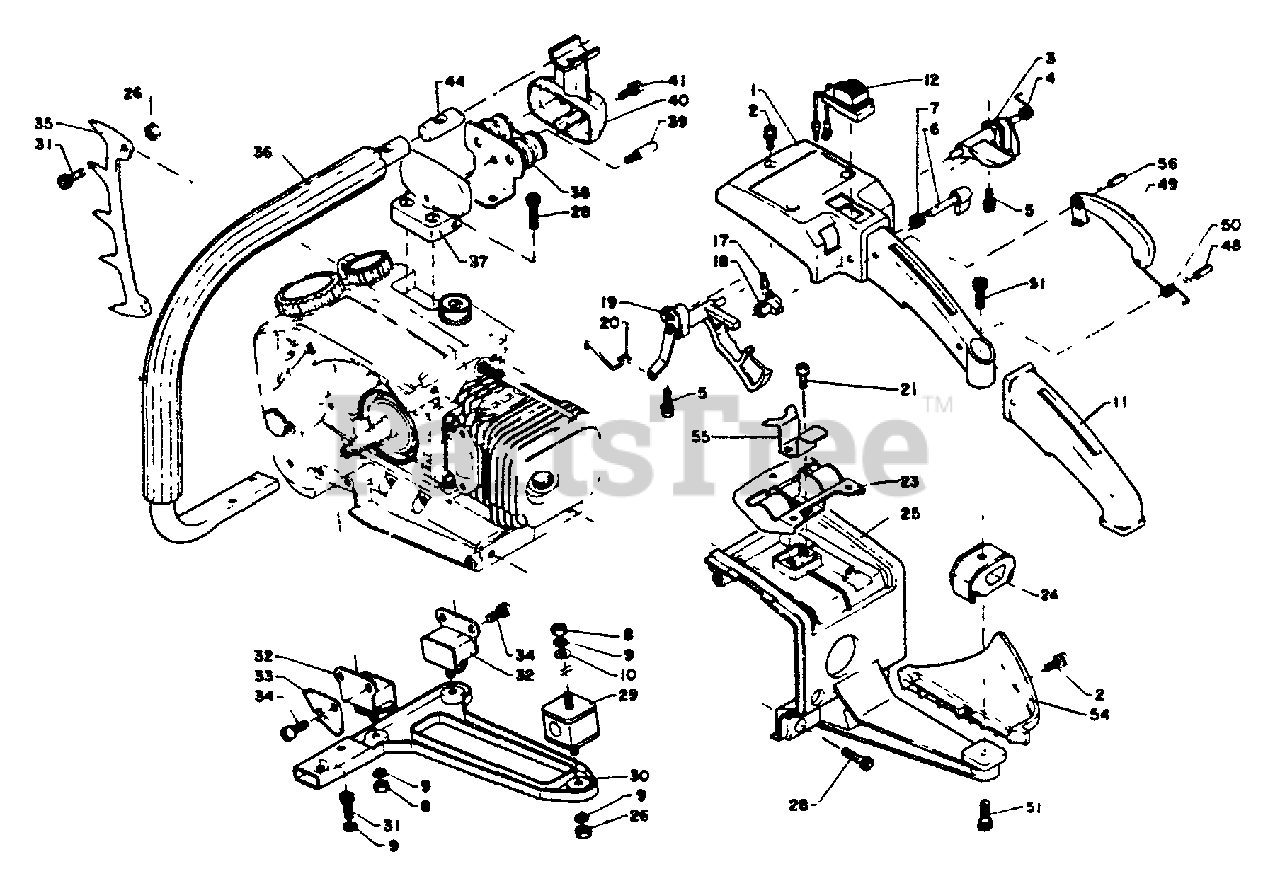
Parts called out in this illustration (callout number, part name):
1	HANDLE, REAR
2	SCREW 4×14
3	PUSH LEVER
5	SCREW 4×14
6	LEVER, THROTTLE
7	SPRING, THROTTLE LOCK
8	NUT M5
9	WASHER, SPRING 5
10	WASHER, FLAT 5.5×10×0.8
11	GRIP
12	IGNITION SWITCH ASSY
17	PIN, LOCKING
18	LOCKOUT, TRIGGER
19	TRIGGER, THROTTLE
20	ROD, THROTTLE
21	SCREW 5×12
24	CUSHION
25	COVER, ENGINE
26	LOCKNUT - 5
28	BOLT 5×20
29	CUSHION RUBBER (L-L: 2)
30	BRACKET, HANDLE - LOWER
31	BOLT 5×12
32	CUSHION RUBBER (L-L)
33	PLATE, WIND PROOF
34	SCREW 5×12
35	BUMPER, SPIKED
36	HANDLE, FRONT
37	CUSHION RUBBER HOLDER
38	CUSHION (L-U)
40	BRACKET, HANDLE - UPPER
41	SCREW 4×10
48	PIN, SPRING 4×13
49	LOCKOUT, THROTTLE
50	SPRING, LOCKOUT RETURN
51	BOLT 5×14
54	HAND GUARD
55	STOPPER
56	PIN, SPRING 4×16
